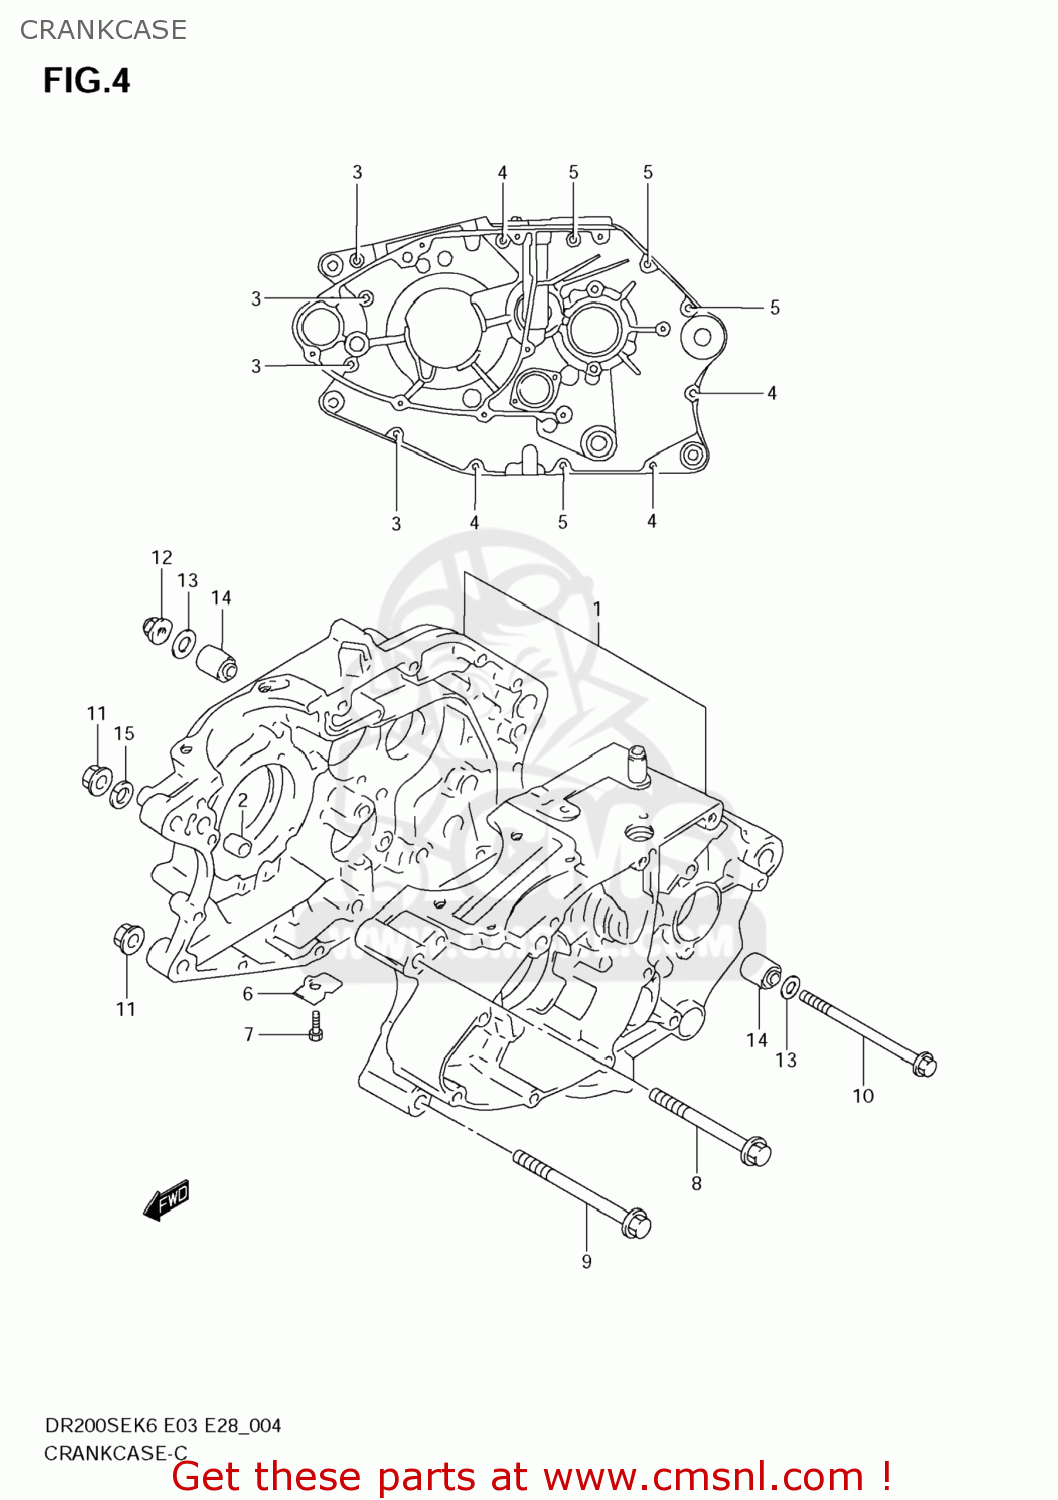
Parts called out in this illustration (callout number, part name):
1	CRANKCASE ASSY
2	PIN
3	BOLT
4	BOLT
5	BOLT
6	PLATE,OIL GALLERY PLUG
7	BOLT
8	BOLT(10X80)
9	BOLT(10X90)
10	BOLT(8X115)
11	NUT
12	NUT
13	WASHER
14	BUSH(8.4X18X16)
15	WASHER,LOCK
